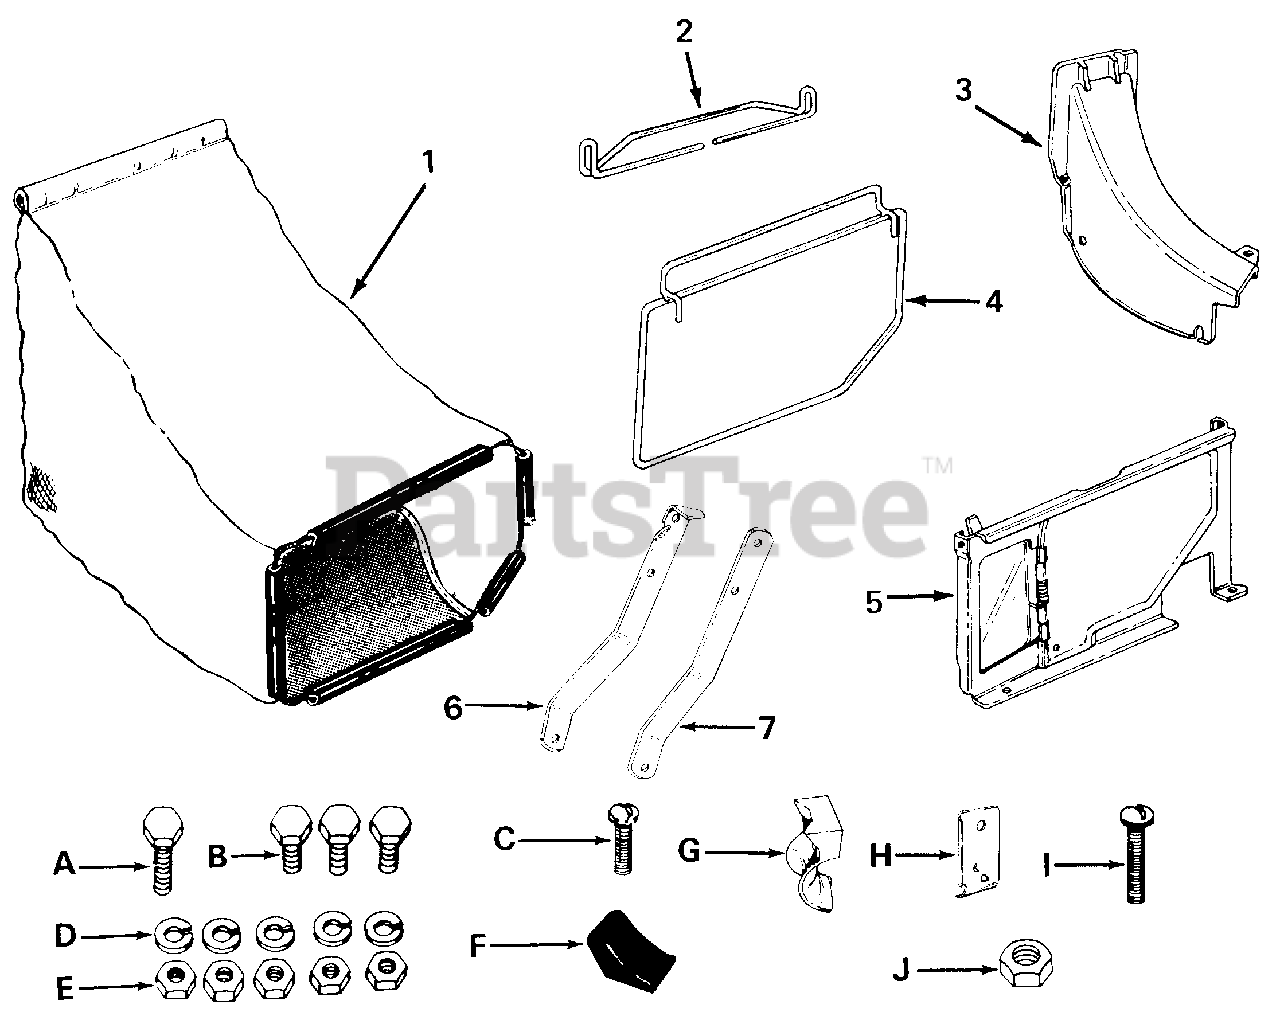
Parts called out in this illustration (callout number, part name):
1	Grass Bag
2	Grass Catcher Handle
3	Top Discharge Chute
4	Front Catcher Frame
5	Top Catcher Panel
6	Panel Support Bracket
7	Panel Support Bracket
A	Hex Bolt 1/4-20 x 5/8" Lg.*
B	Hex Bolt 1/4-20 x 1/2" Lg.*
C	Truss Machine Screw 1/4-20 x 1/2 Lg.*
D	Lock Washer 1/4" I.D.*
E	Hex Nut 1/4-20 Thread*
F	Door Grip
G	Rope Guide Half
H	Rope Retainer Clip
I	Truss Machine Screw 1/4-20 x 1.0" Lg.*
J	Hex Nut 5/16-18 Thread*
